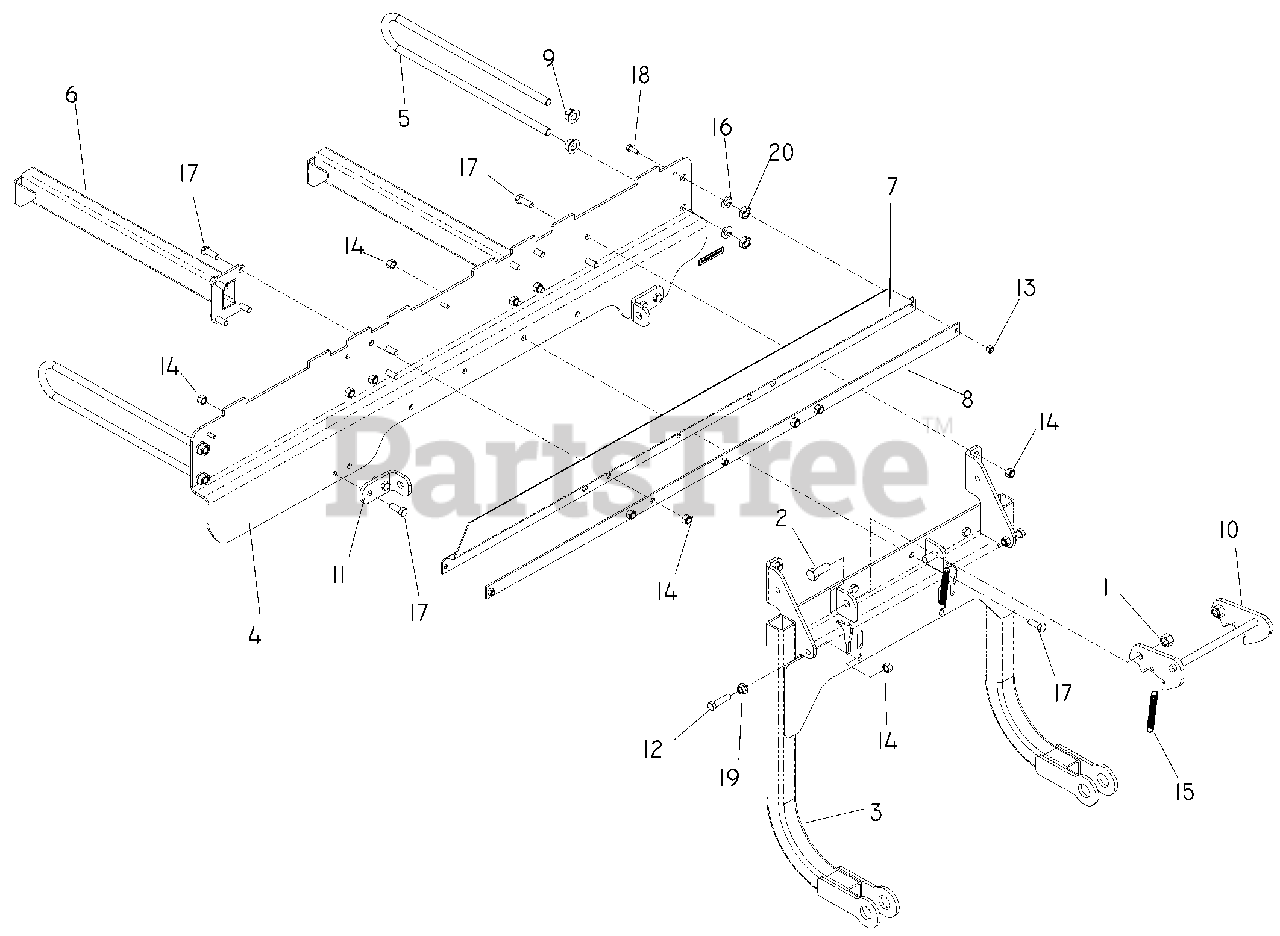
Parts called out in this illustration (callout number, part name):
1	NUT, ½ -13, NYLOC
2	HCS, ½ -13 x 1¼
4	MOUNT Z BRACE
5	SUPPORT, OUTER
6	SUPPORT ARM
7	SEAL, RUBBER
8	SEAL STRAP
9	NUT, ½ -13, WHIZLK
11	BRACKET, SUPPORT
12	HCS, 3/8 -16 x 1½
13	NUT, ¼ -20, NYLOC
14	NUT, 3/8 -16, NYLOC
16	LOCKWASHER, ½
17	HCS, 3/8 -16 x 1
18	HCS, ¼ -20 x ¾
19	NUT, 3/8 -16, WHIZLK
20	NUT, ½ -13, JAM
